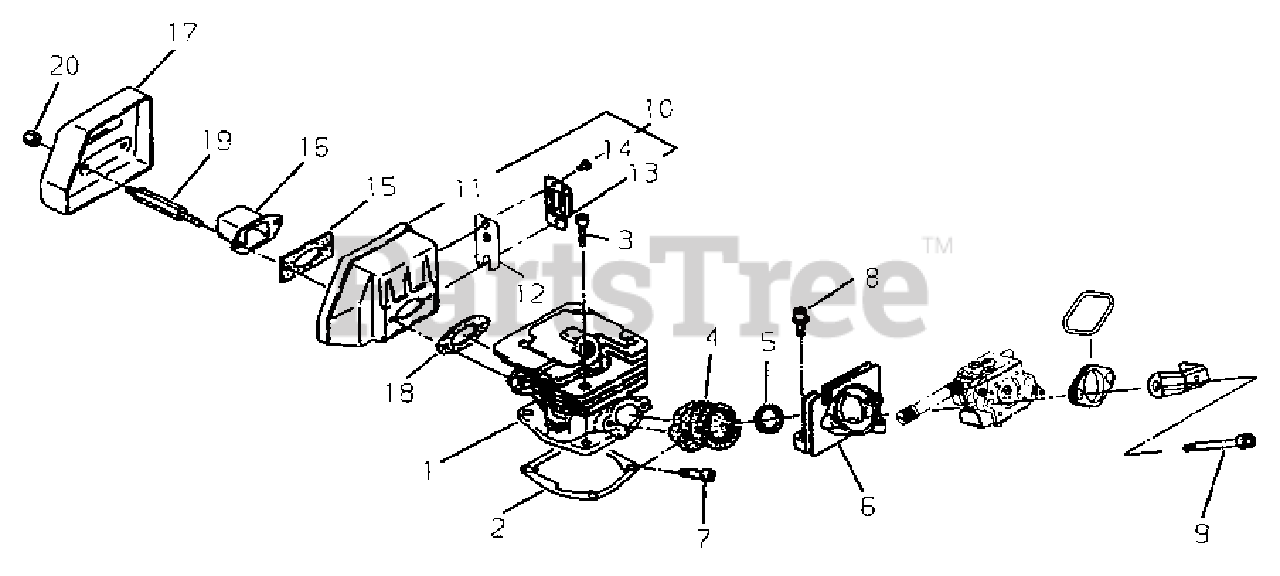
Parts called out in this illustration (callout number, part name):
1	CYLINDER
2	GASKET, CYLINDER
4	BOOT
5	SLEEVE
6	BRACKET
7	SCREW - 4X12
8	SCREW - 4X14
9	SCREW - 5X50
10	BASE MUFFLER ASSY
11	BASE MUFFLER
12	SCREEN, SPARK ARRESTOR
13	GUIDE, EXHAUST
14	SCREW - 4X6
15	PLATE, MUFFLER
16	PIPE, MUFFLER
17	COVER, MUFFLER
18	SHIELD, EXHAUST
19	BOLT
20	NUT
